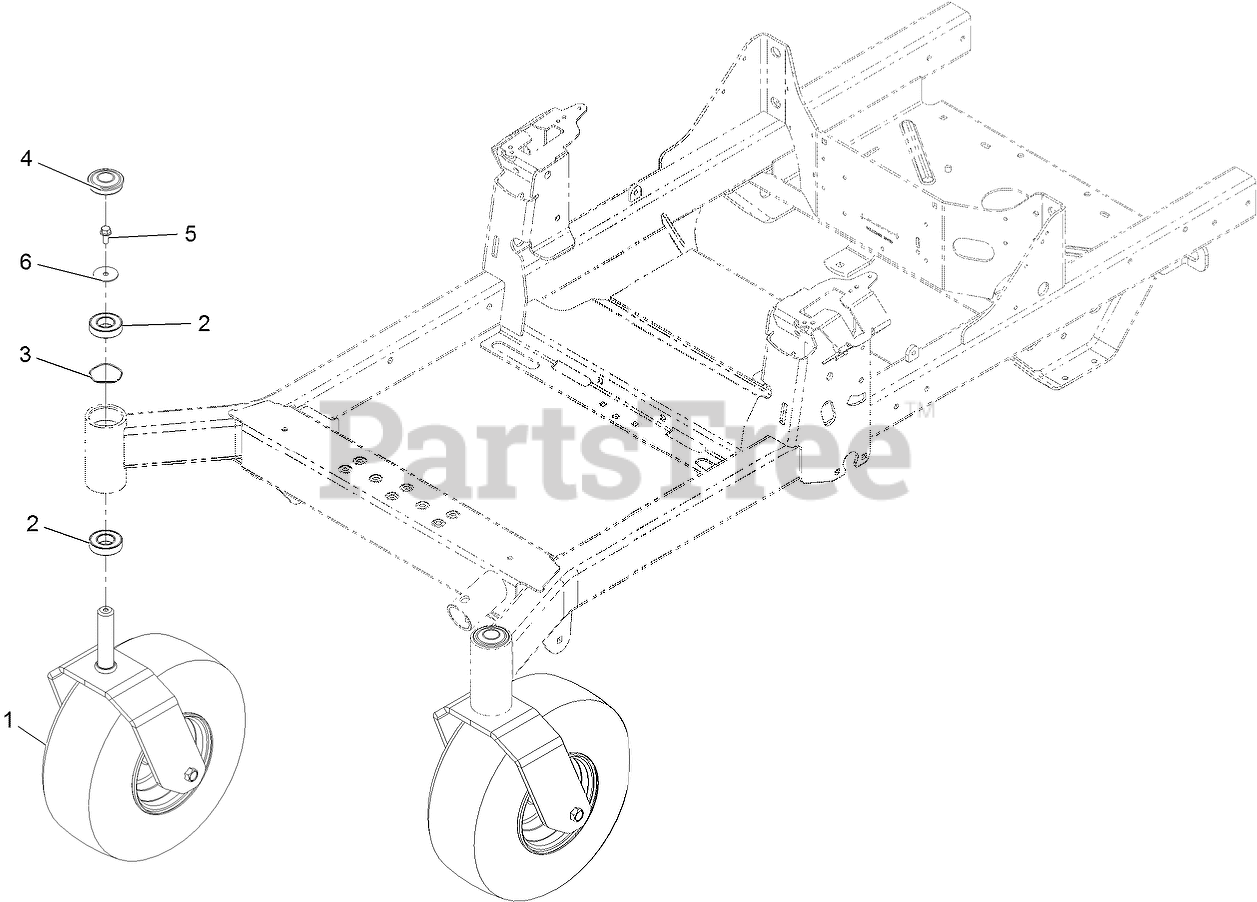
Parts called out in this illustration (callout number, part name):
1	ASM-Front Caster W/Fork
2	BEARING-BALL
4	CAP-GREASE
5	SCREW-HHF
6	WASHER-FLAT
